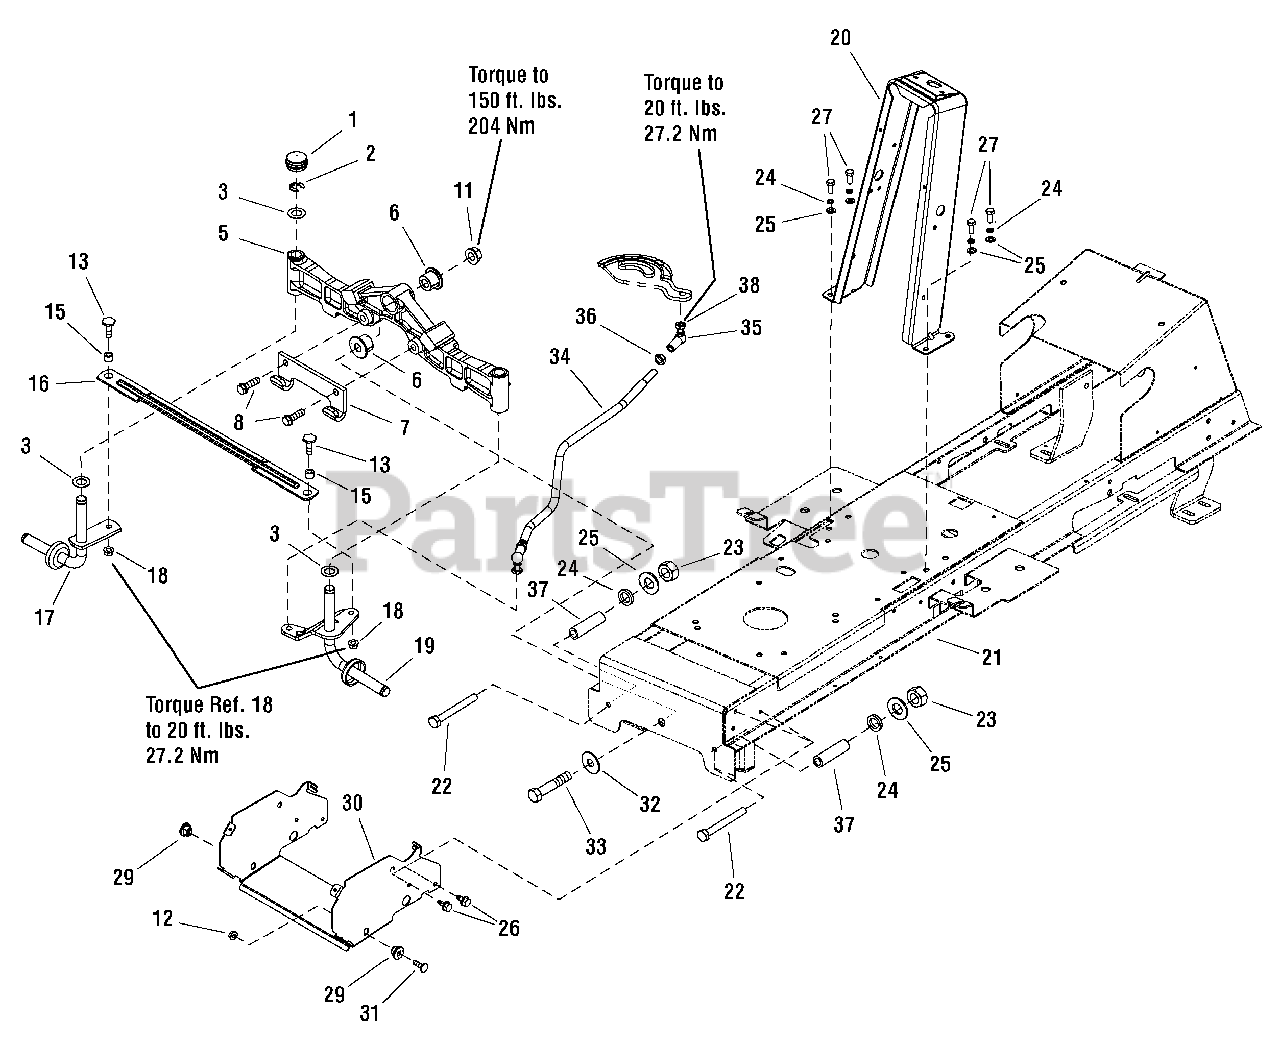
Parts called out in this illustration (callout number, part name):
1	HUB CAP
2	RING, Klipring
3	WASHER, 1-5/8
5	AXLE, Front
6	BUSHING, Axle Pivot
7	HOOK, Hitch 5/16 THK
8	CAPSCREW, 7/16-14 x 1-1/2
11	NUT, Hex Flange 5/8-11
12	NUT, Hex Flange, 5/16-18
13	CAPSCREW, Hex 3/8-16 x 1-1/4
15	SPACER
16	ROD, Tie
17	SPINDLE & CUP ASSEMBLY, Right
18	NUT, Hex Flange, 3/8-16
19	SPINDLE & CUP ASSEMBLY, Left
20	TOWER
22	BOLT, M8 x 75
23	NUT, M8
24	WASHER, 8.4
25	WASHER, 8
26	CAPSCREW, Hex Washer Head, Taptite, 5/16-18 x 5/8
27	BOLT, M8 x 20
29	PIVOT, Hood
30	SUPPORT, Muffler
31	BOLT, Carriage, Short Neck, 5/16-18 x 1
32	WASHER, 5/8
33	CAPSCREW, Hex, 5/8-11 x 3-1/4
34	LINK, Drag
35	BALL JOINT, CS16 M10-M12
36	NUT, M12
37	DISTANCE, Front axle 0-9521-29
38	NUT, M10 DIN6923 8
